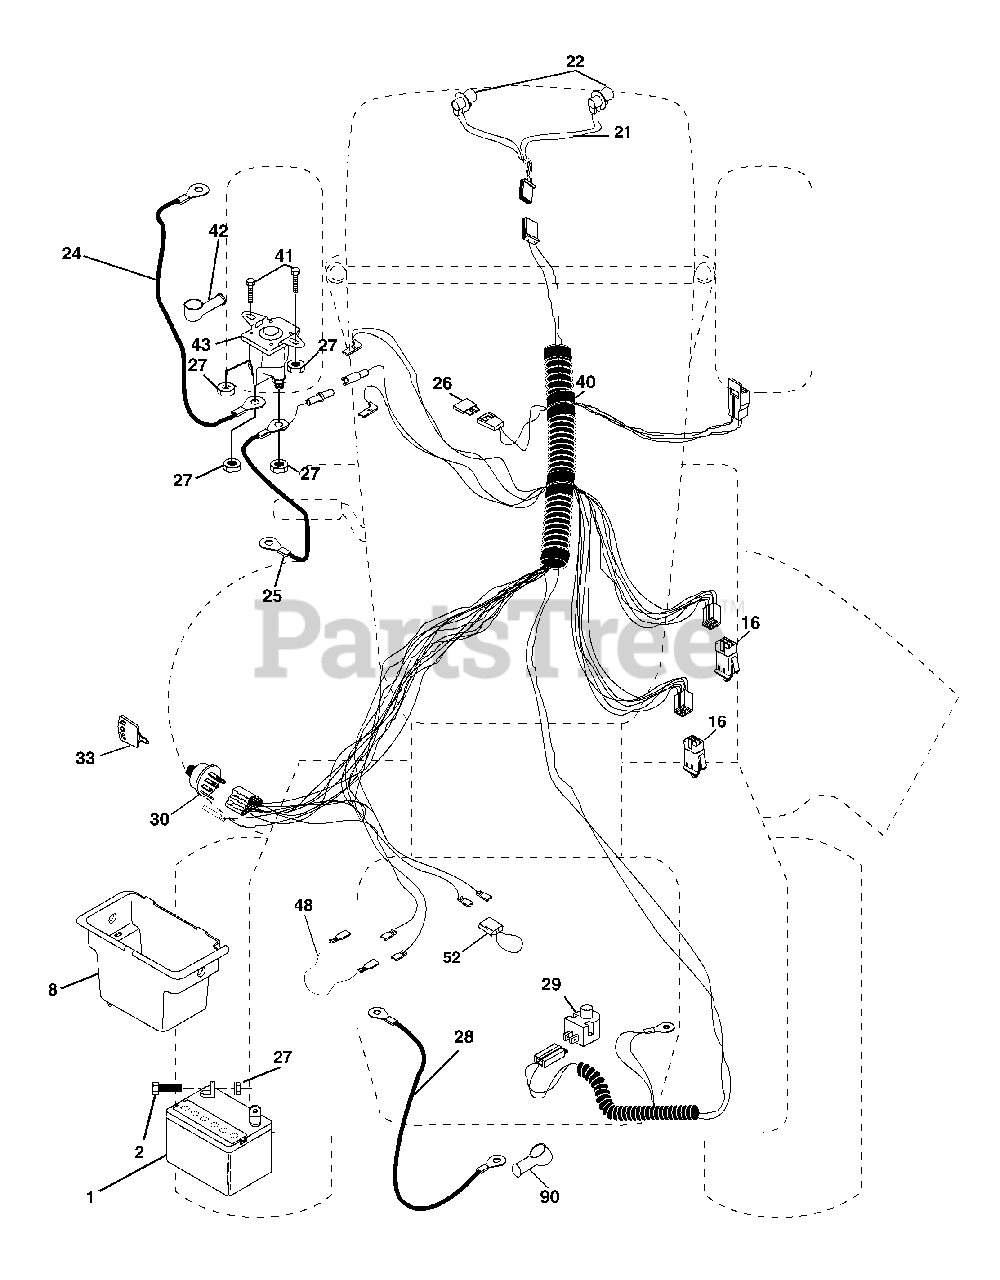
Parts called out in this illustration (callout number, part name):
1	Battery
2	Bolt Hex Hd 1/4-20unc X 3/4
8	Box Battery
16	Switch Interlock
21	Harness Asm Light W/4152j
22	Bulb Light #1156
24	Cable Battery 6 Ga 11" red
25	Cable Battery
26	Fuse 20 AMP
27	Nut Keps Hex 1/4-20 Unc
28	Cable Ground 6 Ga 12" black
29	Switch Plunger Nc Gray
30	Switch Ign
33	Key Ign
40	Harness Ign
41	Bolt Blk Fin Hex 1/4-20
42	Cover Terminal Red
43	Solenoid
48	Adapter Ammeter
52	Protection Wire Loop
90	Cover Terminal Battery
